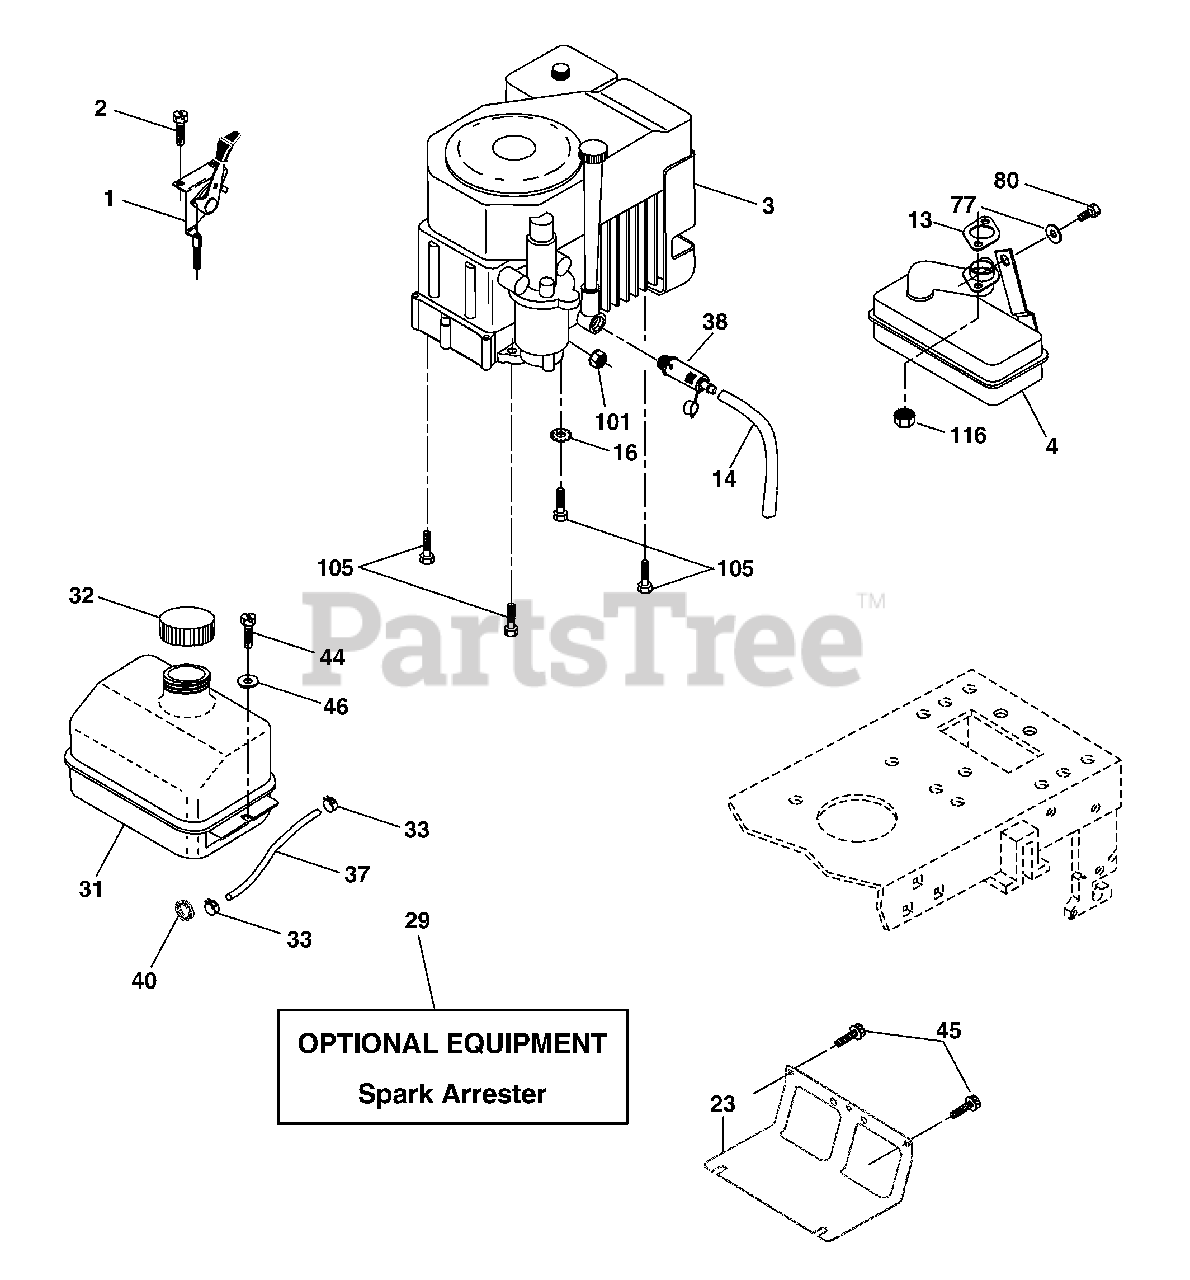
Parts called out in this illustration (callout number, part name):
1	Control Th/ch Flag
2	Screw Hex Thd Cut 1/4-20 x 1/2
13	Gasket Eng
14	Tube Drain Oil Easy
16	Washer Lock Ext Tooth 3/8
23	Shield Brn/Dbr Guard
29	Kit Spark Arrestor (Flat Scrn)
31	Tank Fuel Front
32	Cap Asm Fuel W/sym Vented
33	Clamp Hose Black
37	Line Fuel 20"
38	Plug Drain Oil Easy
40	Bushing Snap Nyl Blk Fuel Line
44	Screw Hexwsh Thdrol 1/4-20 x 3/4
45	Screw Hexwsh Thdr 3/8-16 x 3/4
46	Washer 9/32 x 7/8 x 16 Ga
77	Washer 5/16 x 3/4 x 16 Ga.
80	Bolt Hex Hd 5/16-18 x 1/2
101	Nut Flange M8 1.25
105	Screw 3/8-16 x 1
116	Nut Hex Flange Toplock M8-1.25
